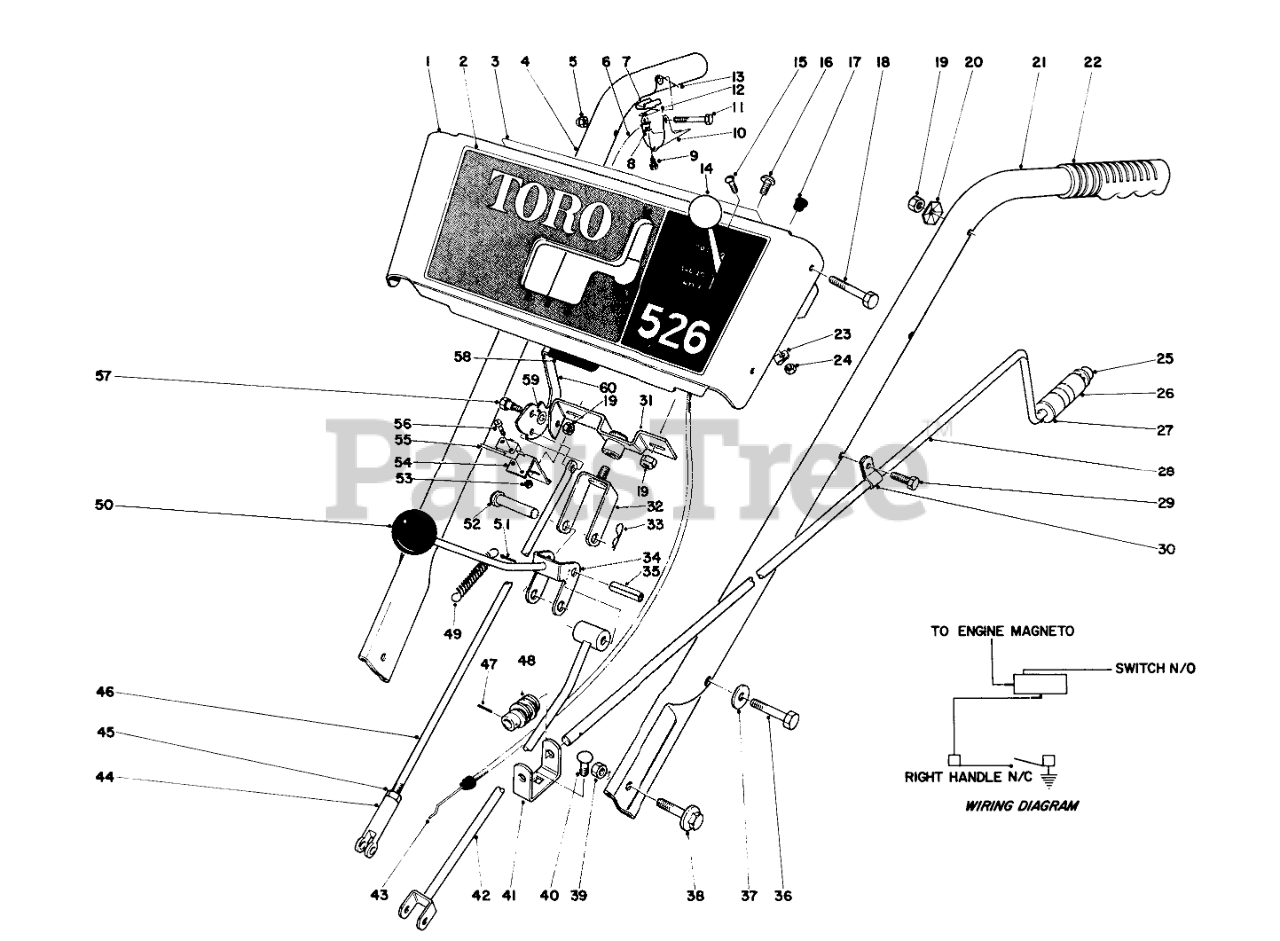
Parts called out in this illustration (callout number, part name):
1	Escutcheon Plate (Incl. Ref. #2 and 3)
2	Decal-Escutcheon
3	Decal
4	Handle Right
5	NUT-CAP
6	Wire Harness
7	Insulator
8	WASHER INSULATOR
9	Screw
10	Safety Lever
11	SCREW-HH
12	INTERLOCK CONTACT
13	INTERLOCK SPRING
14	KNOB-CONTROL
15	SCREW-PPH
16	Screw, Machine
18	SCREW-HH
19	NUT-LOCK
20	Washer
21	Handle Left
22	Grip Handle
23	Clip
24	Nut
25	Speed Nut
26	Chute Control Grip
27	WASHER-FLAT
28	ROD CHUTE CONTROL
29	Hex Hd. Screw
30	R-CLAMP
31	SWIVEL BLOCK WA
32	Pivot Bracket
33	PIN-HAIR
34	Rod Shift
35	PIN-ROLL
36	SCREW-HH
37	WASHER-FLAT
38	SCREW-HHF
39	NUT-HEX
40	SCREW-CARR
41	WORM BRACKET
42	Trunnion
43	Control-Throttle
44	Clevis
45	NUT-HJ
46	Drag Link
47	PIN-SPRING
48	GEAR-WORM, CHUTE
49	CONT ROD SPRING 0
51	PIN-COTTER
52	PIN-CLEVIS
53	NUT-LOCK, NI
54	Bracket Switch
55	MICRO SWITCH
56	SCREW-HEAD, PAN
57	SCREW-SHOULDER
58	AUGER CLUTCH HND GRIP
59	WASHER-FLAT
60	Auger Clutch Handle
